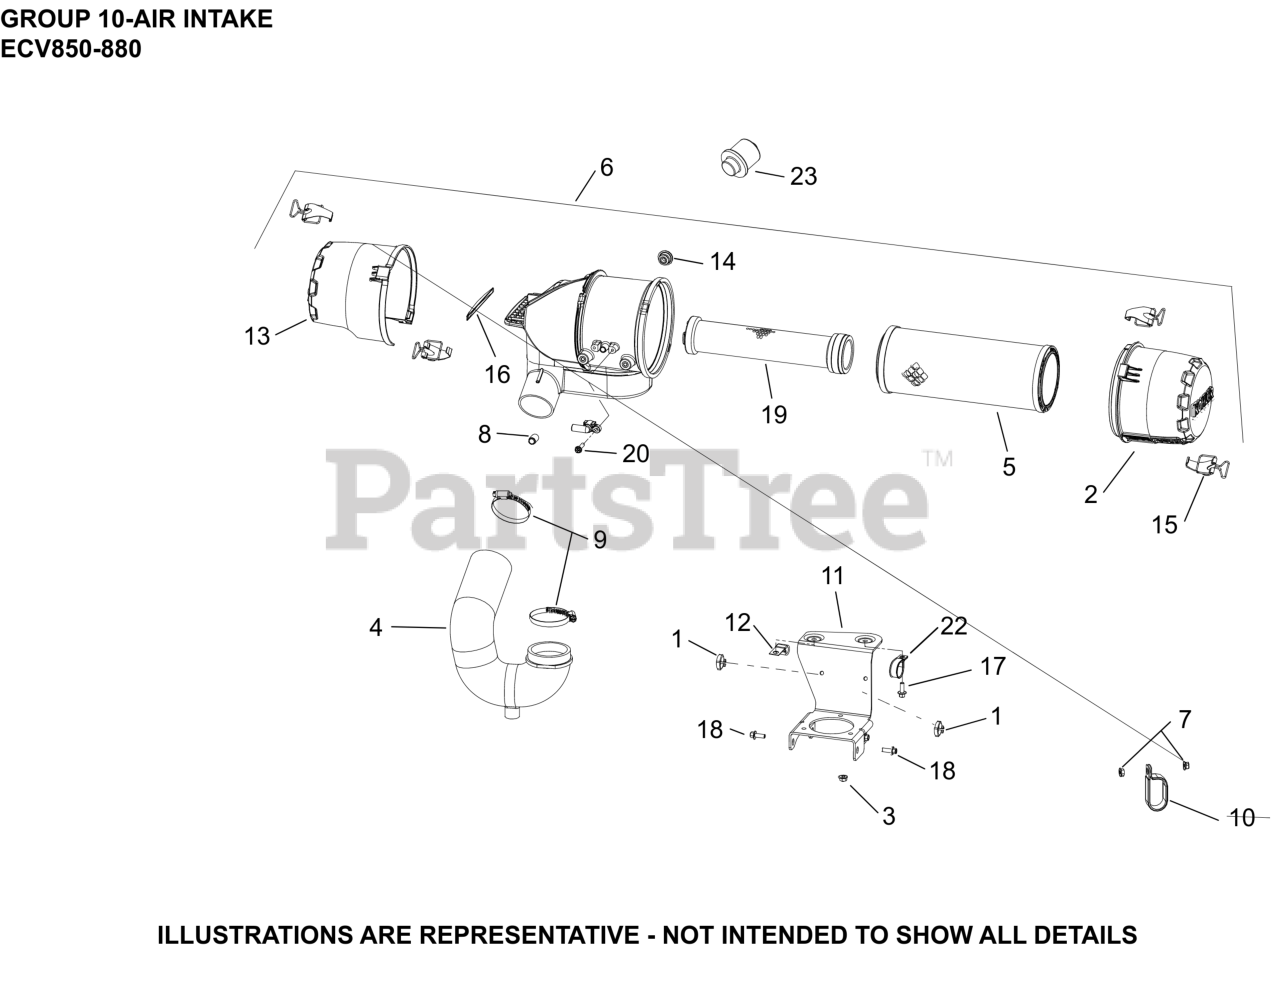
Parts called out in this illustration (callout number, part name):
2	COVER, AIR FILTER
3	NUT, FLG M6X1.0
4	HOSE, AIR CLEANER
5	ELEMENT, AIR FILTER - PRIMARY
6	FILTER ASSEMBLY, AIR
7	NUT, HEX FLANGE
8	CAP, MASKING
9	NUT, HEX FLANGE
9	CLAMP, HOSE
10	CLAMP, INSULATED DOUBLE
11	BRACKET, HDAC SUPPORT
12	CLIP, CABLE (KM)
13	COVER, RAIN CAP
14	PLUG, HOLE
15	CLIP ASSEMBLY
16	DAMPER, FOAM INSERT
17	SCREW, FLG M6X1.0X16
18	SCREW, FLG M6X1.0X16
NI	BODY, THROTTLE ASSEM. 34 DIA.(.3 OFFSET)
